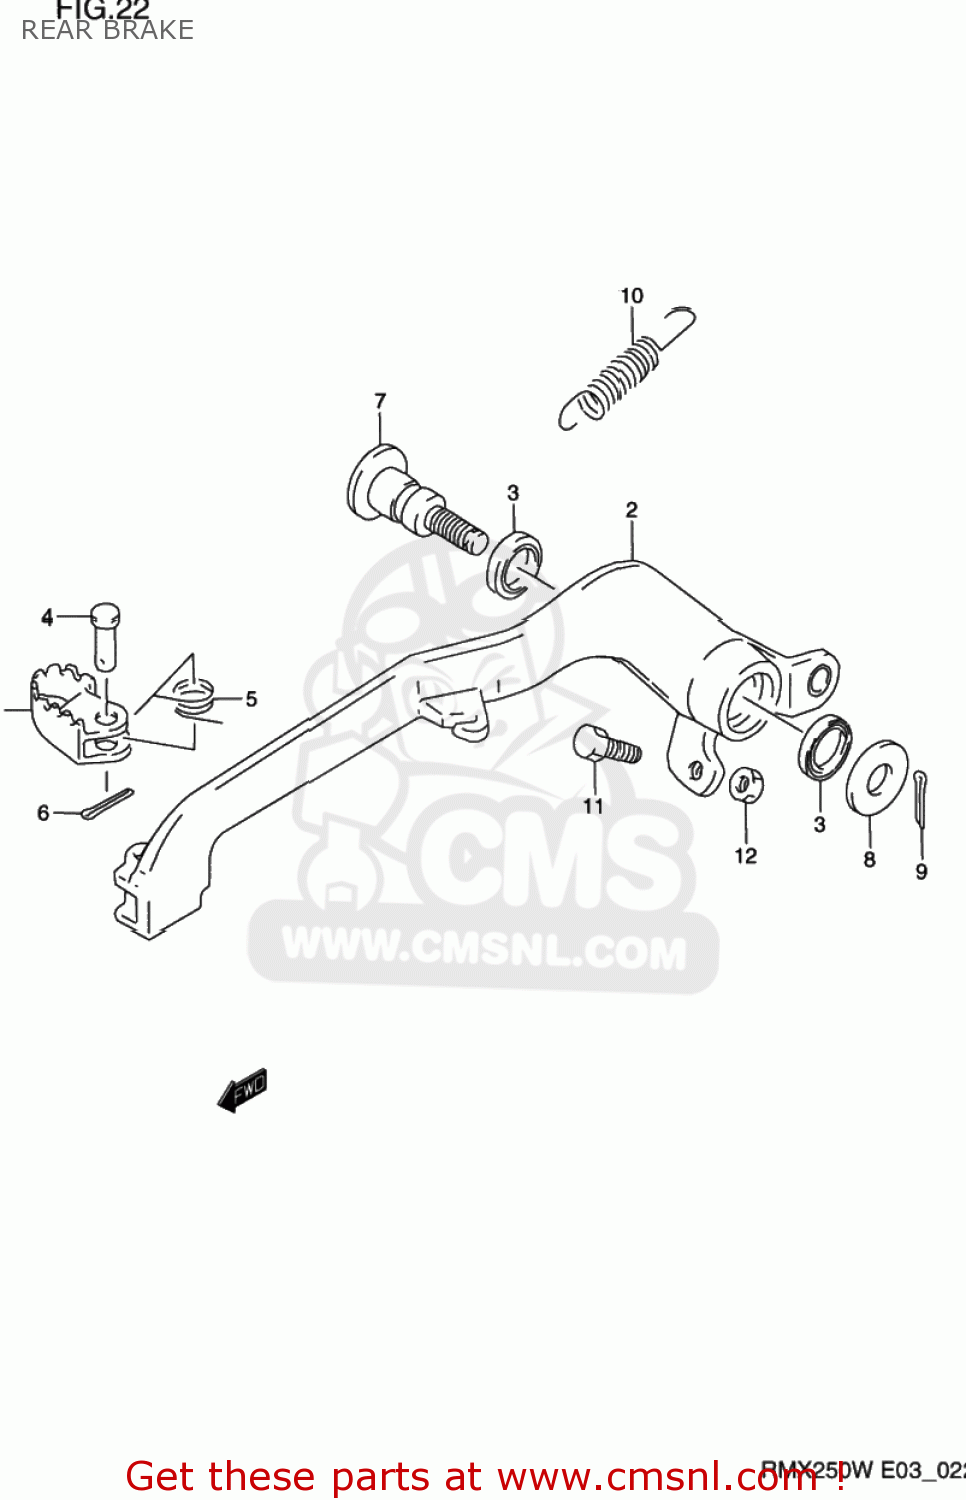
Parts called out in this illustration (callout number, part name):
1	PEDAL,BRAKE
2	ARM,BRAKE PEDAL
3	SEAL,OIL(15X21X3)
4	PIN(6X23.5)
5	SPRING
6	PIN
7	SHAFT,BRAKE PEDAL
8	WASHER
9	PIN 20X20
10	SPRING
11	BOLT(6X23)
12	NUT 6MM
